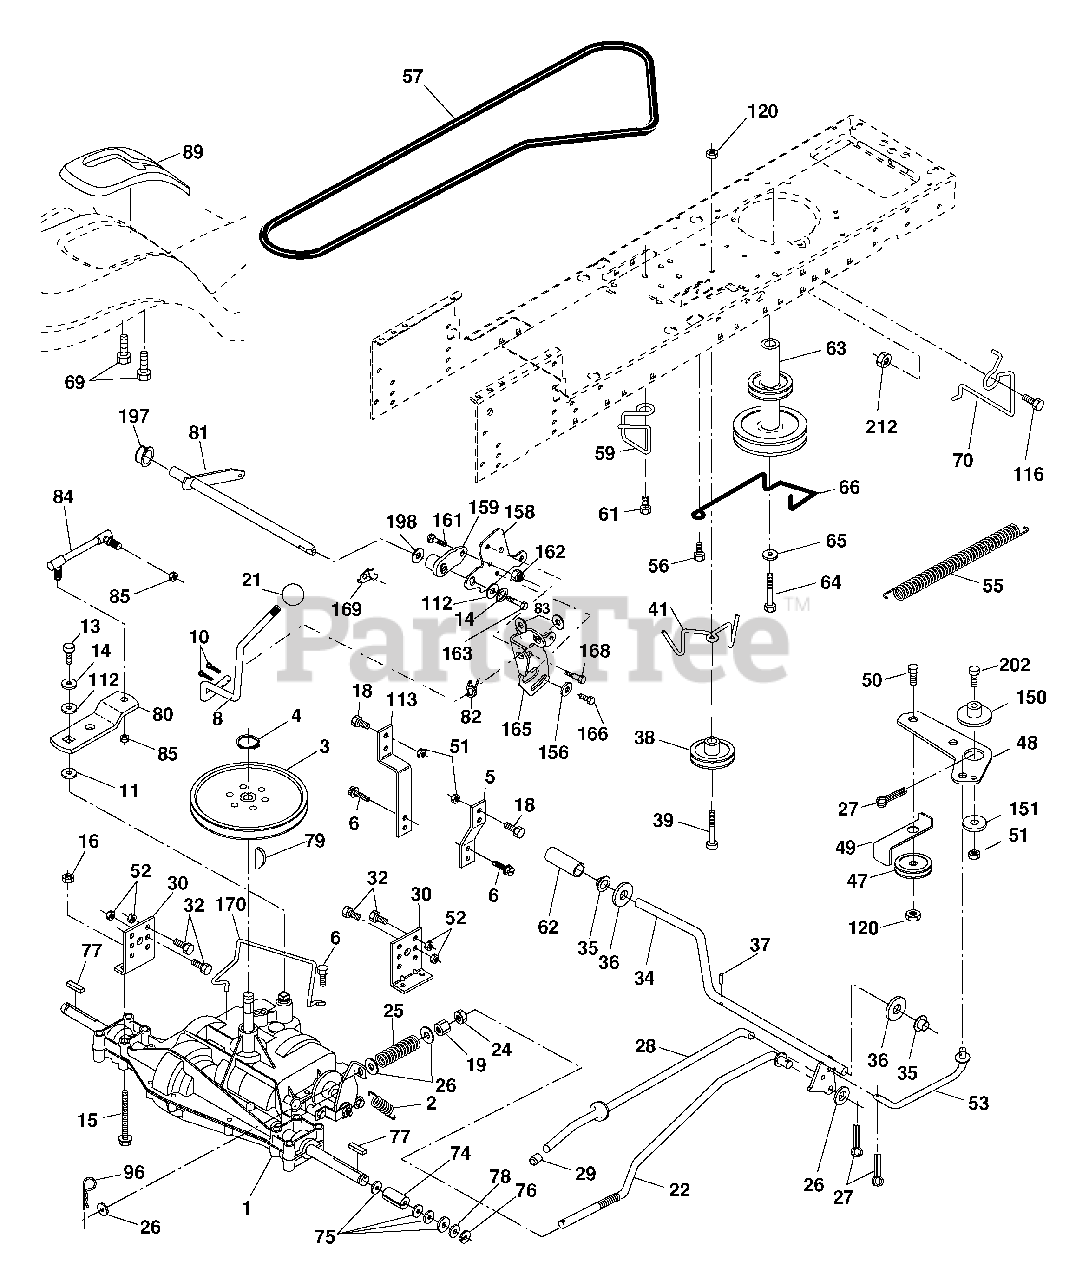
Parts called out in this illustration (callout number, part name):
2	Spring Return Brake
3	Pulley Transaxle 18"tires
4	Ring Retainer # 5100-62
5	Strap Torque 30 Degrees RH
6	Screw 5/16-18 x 3/4
8	Rod Shifter Blk
10	Pin Cotter 1/8 x 1 Cad
11	Washer Plate Shf 388 Sq Hole
13	Bolt 1/4-28 unf Gr. 8 w/Patch
14	Washer Lock Hvy Helical 1/4
15	Bolt Hex Flghd 5/16-18 Gr. 5
16	Nut 5/16-18
18	Bolt Fin Hex 3/8-16 unc x 1 Gr. 5
19	Nut lock Hex w/Ins 3/8-16 Unc
21	Knob
22	Rod Brake LT
24	Nut Hex Jam 3/8-16 unc
25	Spring Rod Brake 2 00 Zinc
26	Washer 13/32 x 13/16 x 16 Ga.
27	Pin Cotter 1/8 x 3/4 Cad
28	Rod Brake Parking LT/YT
29	Cap Brake Parking Black
30	Bracket Transmission
32	Bolt Fin Hex 5/16-18 x 3/4
34	Shaft Asm Pedal Foot Nibbed
35	Bearing Nylon Blk 629 Id
36	Washer 21/32 x 1 x 16 Ga.
37	Pin Roll 3/16 x 1"
38	Pulley Composite Flat
39	Bolt 3/8-16 x 2-3/4
41	Keeper Belt Idler
47	Pulley Idler V Groove Plastic
48	Bellcrank Clutch Grnd Drv STL
49	Retainer Belt Style Spring
50	Bolt Carr Sh 3/8-16 x 1-1/2 Gr. 5
51	Nut Crownlock 3/8-16 unc
52	Nut Crownlock 5/16-18 unc
53	Link Clutch
55	Spring Return Clutch 6 75
56	Screw 3/8-16 x 1-1/4
57	V-Belt Ground Drive 95
59	Keeper Belt Chassis Span Ctr
61	Screw 3/8-16 x .875
62	Cover Pedal Blk Round
63	Engine Pulley LT/YT
64	Bolt Hex 7/16-20 x 4 Gr. 5
65	Washer Lock Hvy Hlcl Spr 7/16
66	Keeper Belt Engine
69	Screw 1/4 x 1/2 unc
70	Guide Belt Mower Drive RH
74	Spacer Axle
75	Washer 25/32 x 1 1/4 x 16 Ga.
76	E-ring #5133-75
77	Key Square 2 0 x 1845/ 1865
78	Washer 25/32 x 1-5/8 x 16 Ga.
79	Key Woodruff
80	Arm Shift Transaxle
81	Shaft Asm Cross Taper
82	Spring Torsion Shift
83	Washer 17/32 x 3/4 x 16 Ga.
84	Link Transaxle
85	Nut Lock Center 1/4-28
89	Console Shift
96	Retainer Spring 1"
112	Washer 9/32 x 3/4 x 10 Ga.
113	Strap Torque 90 Degrees LH
116	Bolt Rdhd Sq Neck 3/8-16 x 1
120	Nut Lock Flg 3/8-16
150	Spacer Retainer Lt
151	Washer 13/32 x 2 x 10 Ga.
156	Washer Srrrtd 5/16 ID x 1.0 x .125
158	Bracket Shift Mount
159	Hub Shift
161	Bolt 1/4-20 x 3/4 Gr. 5
162	Nut Crownlock 1/4-20 unc
163	Bolt Hex Fin 1/4-20 unc x 1 Gr. 5
165	Bracket Pivot Lever
166	Screw 5/16-18 x 5/8
168	Bolt Shoulder 5/16-18 x .561
169	Plate Fastening
170	Keeper, Belt Transaxle
197	Nyliner Snap-In 5/8
198	Washer Nylon
202	Bolt Carr Sh 3/8-16 x 1-3/4 Gr. 5
212	Nut Hex Flg Lock
263	Screw 3/8-16 x 3/4
